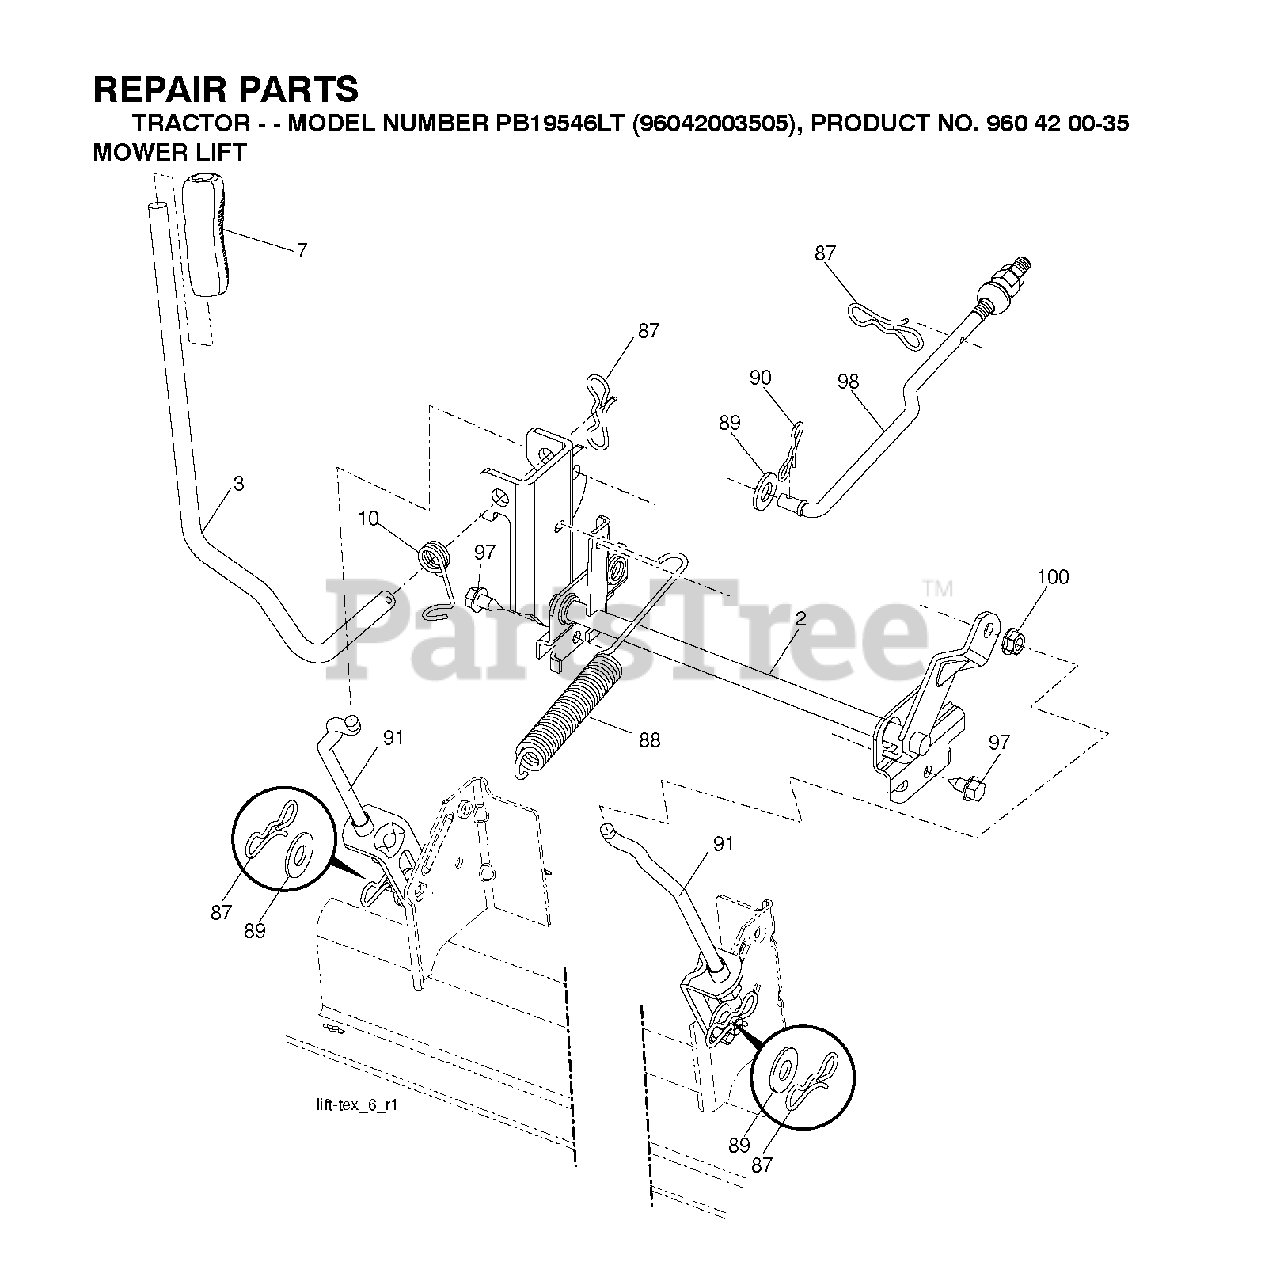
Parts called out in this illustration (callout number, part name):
2	SHAFT.ASM.CROSS.LIFT
3	LEVER.LIFT.HANDLE.LT
7	GRIP.HANDLE.LIFT.PVC.BLACK
10	SPRING.TORSION.LIFT.HANDLE
50	LINK.ASM.LIFT.FIXE.38/42/46"
87	PIN.COTTER.7/16.BOW TI.
88	SPRING.LIFT.ASSIST
89	WASHER.CLEAR.ZINC
90	PIN.COTTER.5/16.BOW TI
91	LINK.ASM.LIFT.REAR
97	SCREW, 3/8-16X3/4
98	LINK.ASM.SUSP.FRONT.MW
100	LOCKNUT
